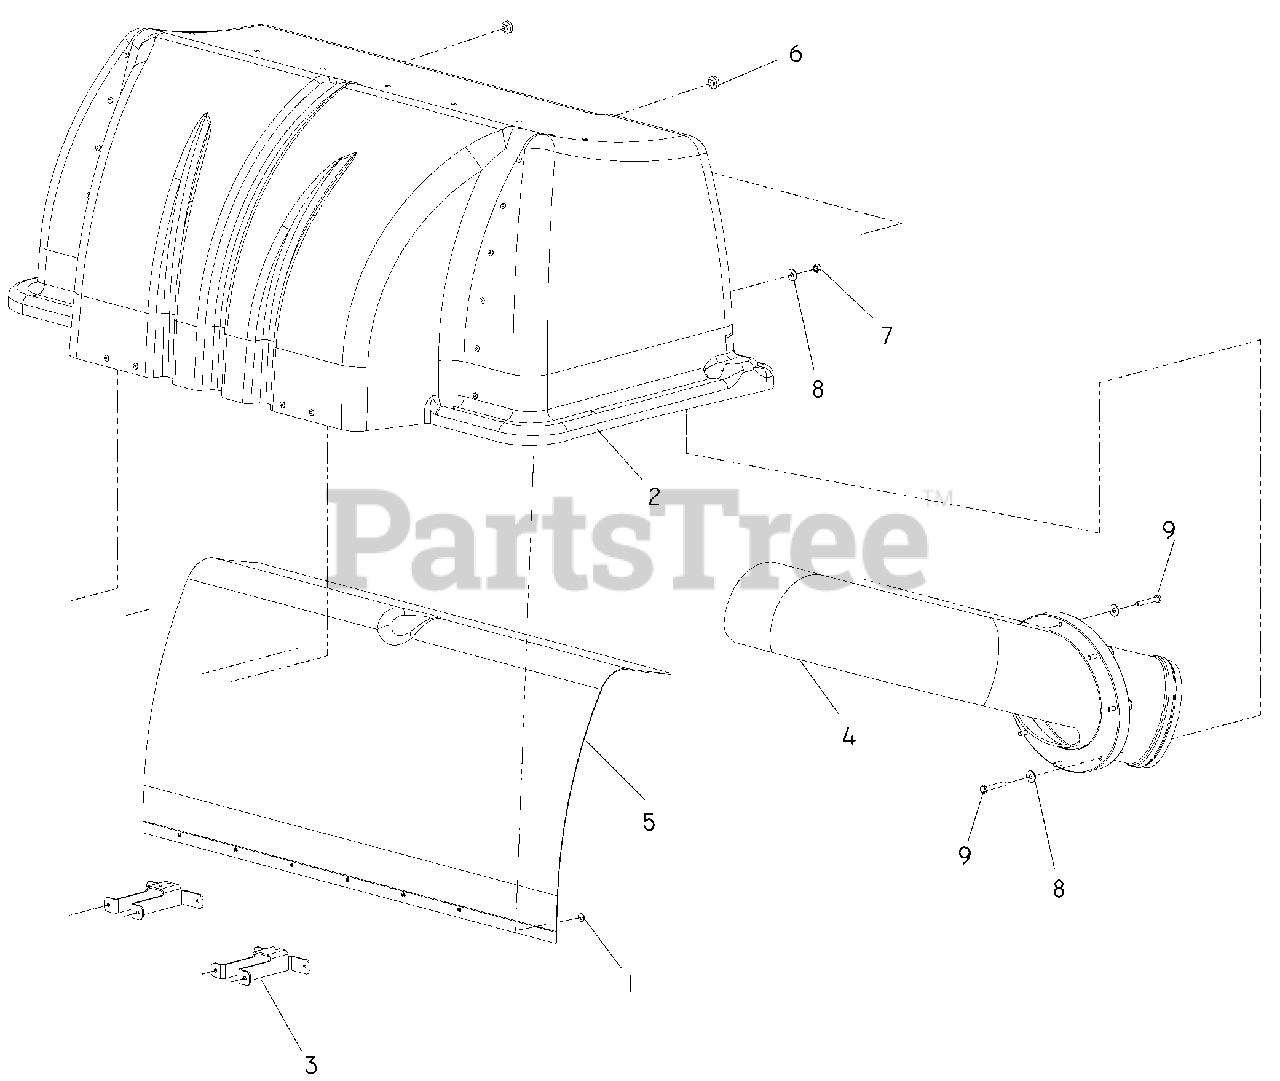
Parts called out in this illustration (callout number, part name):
1	WASHER, #10
3	SUPPORT, DRAW LATCH
4	INLET TUBE
5	MESH, POLY DIAMOND
7	NUT, ¼ -20, NYLOC
8	WASHER, ¼
9	HCS, ¼ -20 x 1¾
